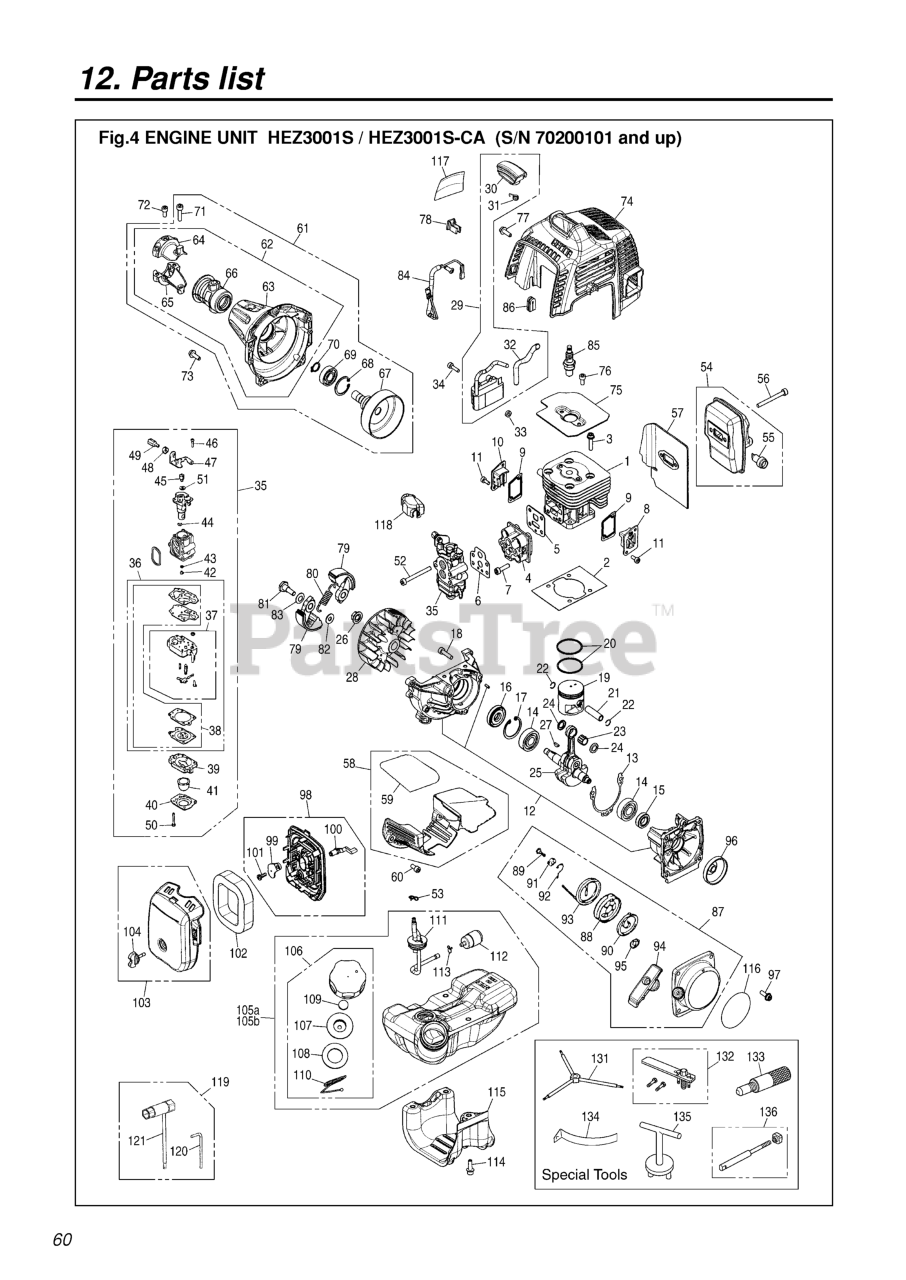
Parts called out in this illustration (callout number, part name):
1	CYLINDER
2	GASKET, BASE
3	BOLT TORX
4	INSULATOR
5	GASKET, INSU
6	GASKET
7	BOLT, TORX
8	COVER, TRS
9	GASKET, TR
10	COVER, TRF
11	BOLT
12	CRANKCASE COMP
13	GASKET, CASE
14	BEARING
15	SEAL
16	SEAL
17	SNAP RING
18	BOLT TORX
19	PISTON
20	RING
22	SNAP RING
23	BEARING
24	WASHER
25	CRANKSHAFT COMP
26	NUT
27	KEY
28	ROTOR
29	COIL ASSY
30	CAP
31	SPRING
33	SPACER
34	BOLT TORX
35	CARBURETOR ASSY
36	REBUILD KIT
37	BODY ASSY
38	GASKET KIT
39	BODY
40	COVER
41	PUMP
42	JET
43	O-RING
44	RING
45	SWIVEL
46	SCREW
48	NUT
49	SCREW
50	SCREW
51	WASHER
52	BOLT TORX
53	CLIP
54	MUFFLER ASSY
55	ARRESTER
56	BOLT TORX
57	GASKET, MUFF
58	PLATE ASSY
59	SHEET
60	BOLT TORX
61	HOUSING ASSY
62	HOUSING COMP.
63	HOUSING
64	BRACKET (A)
65	BRACKET (B)
66	CUSHION
67	DRUM
68	RING
69	BEARING
70	SNAP RING
71	BOLT TORX
72	BOLT TORX
73	BOLT TORX
74	COVER, ENGINE
75	PLATE, CYL
76	BOLT TORX
77	BOLT, TORX
78	CLAMP
79	SHOE
80	SPRING
81	SCREW
82	WASHER
83	WASHER
84	CORD COMP.
85	SPARK PLUG
86	GROMMET
87	RECOIL ASSY
88	REEL
89	SCREW
90	SPRING
91	COLLAR
92	ARM
93	ROPE
94	KNOB
95	PLATE
96	PULLEY
97	BOLT, TORX
98	BODY ASSY
99	PLATE, CHOKE
100	LEVER
101	SCREW
102	ELEMENT
103	COVER ASSY
104	KNOB
105A	TANK ASSY
106	CAP ASSY
107	HOLDER ASSY
108	PACKING
109	FILTER
110	STOPPER
111	PIPE COMP
112	FILTER ASSY
113	CLIP
114	BOLT TORX
115	GUARD, TANK
116	LABEL, RECOIL
117	LABEL, COVER
118	COVER
119	TOOL SET
120	BAR
121	SOCKET
131	HEXAGON WRENCH
132	PULLER ASSY
133	STOPPER
135	PULLER
136	ROD ASSY
